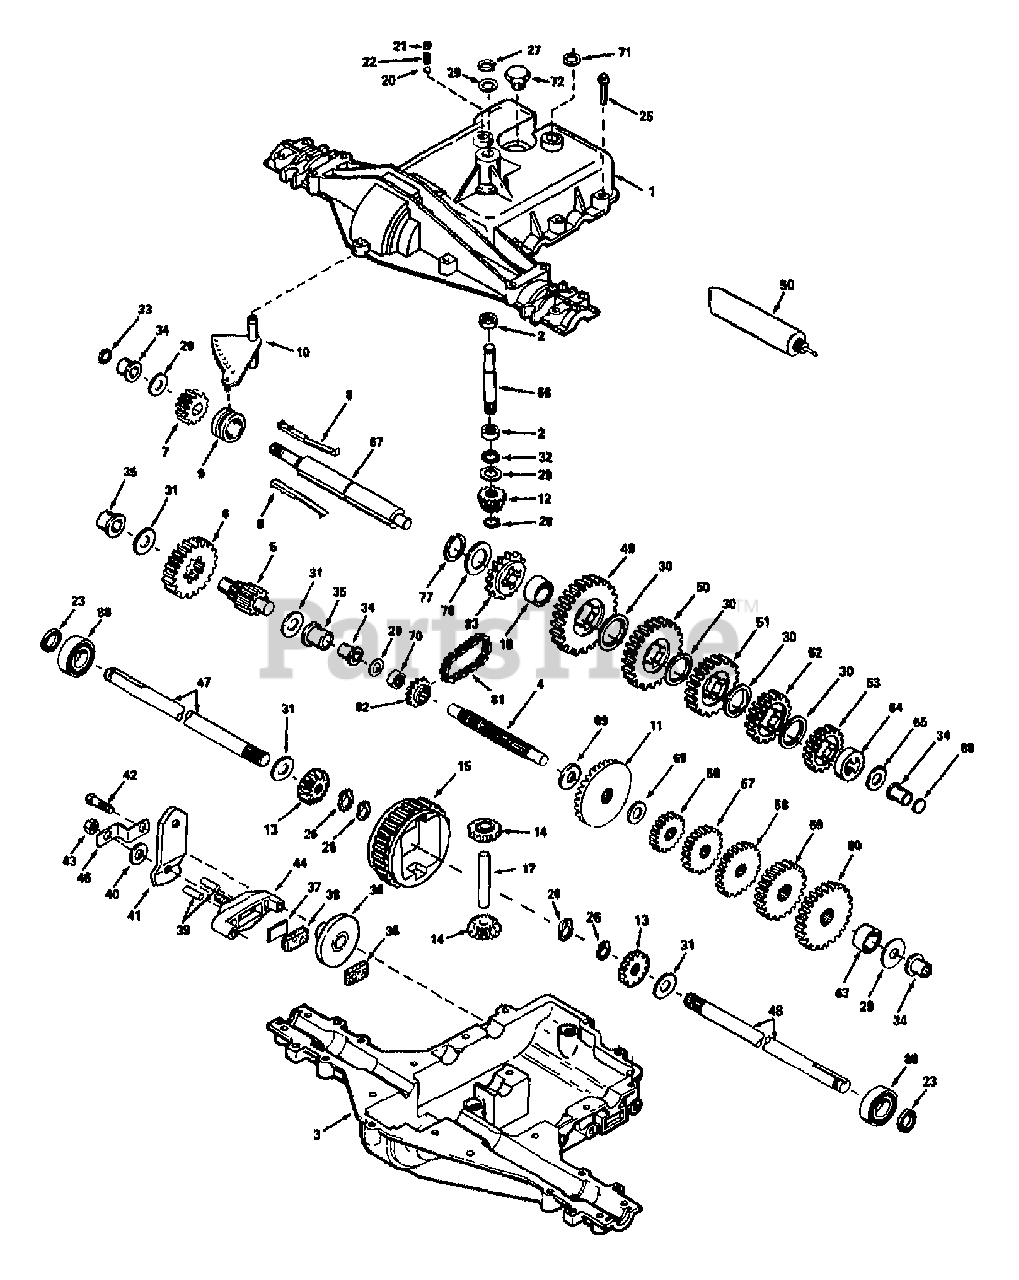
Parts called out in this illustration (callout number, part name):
1	COVER, TRANSAXLE
2	NEEDLE BEARING
4	COUNTERSHAFT
5	SHAFT & GEAR
6	OUTPUT GEAR
7	SPUR GEAR
8	SHIFT KEY
11	BEVEL GEAR
12	INPUT PINION
13	BEVEL GEAR
14	BEVEL GEAR
15	RING GEAR
17	DRIVE PIN
22	SPRING
23	SEAL
26	RET RING
27	RET RING
28	RET RING
29	WASHER
30	WASHER
32	O RING
33	SQUARE CUT RING
34	BUSHING
36	BRAKE DISK
37	BRAKE PAD PLATE
38	BRAKE PAD
39	DOWEL PIN
41	BRAKE LEVER
49	SPUR GEAR
50	SPUR GEAR
51	SPUR GEAR
52	SPUR GEAR
53	SPUR GEAR
56	SPUR GEAR
57	SPUR GEAR
58	SPUR GEAR
59	SPUR GEAR
60	SPUR GEAR
67	BRAKE SHAFT
77	RET RING
81	ROLLER CHAIN
82	SPROCKET
83	SPROCKET
